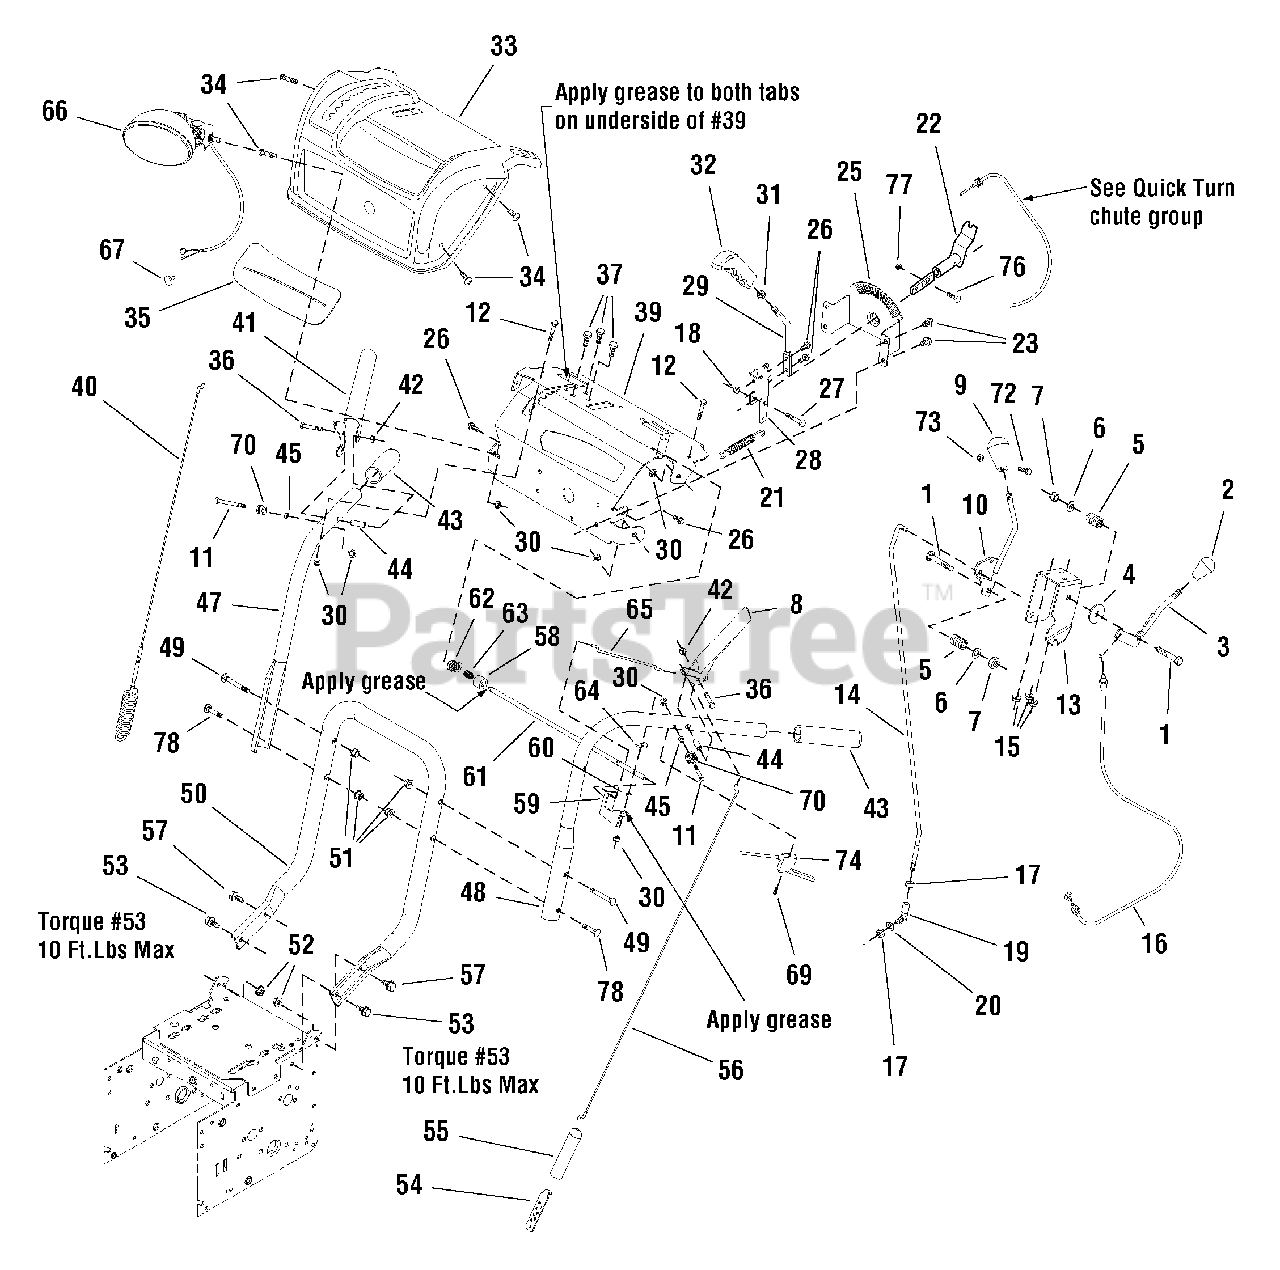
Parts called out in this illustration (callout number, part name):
1	CAPSCREW, Hex Head 3/8-16 x 2 G5
2	KNOB, Interior Thread 3/8-16
3	ROD, 3/8 Diameter 5" Large, 3/8-16 x 1 Chute
4	WASHER, 3/8
5	SPRING
6	WASHER, 3/8
7	NUT, Hex Lock ESNA Light 3/8-16
8	HANDLE, Clutch L.H.
9	KNOB, Slot Speed
10	ROD & PLATE ASSEMBLY, Speed Control
11	CAPSCREW, Hex Head 1/4-20 x 2-1/2 G5
12	CAPSCREW, Hex Head 1/4-20 x 1-3/4 G5
13	BRACKET, Trac & Deflector Control
14	ROD, Speed Control
15	NUT, Hex Flange 5/16-18, Whiz Lock, Small
16	CABLE, Deflector Control
17	NUT, Hex 5/16-24
18	NUT, Hex Flange 1/4-20 Centerlock Large
19	BALLJOINT, Steel
20	LOCKWASHER, Spring 5/16
21	SPRING, Extension
22	TUBE & BRACKET ASSEMBLY, Cable Support
23	SCREW, Hex Washer Head Taptite 5/16-18 x 1/2
25	SUPPORT, Chute Control 14GA
26	SCREW, Hex Washer Head Taptite 1/4-20 x 5/8
27	BOLT, Shoulder 1/4-20
28	BRACKET, Support Quick Turn
29	ROD, Chute
30	NUT, Hex Lock ESNA Light 1/4-20
31	NUT, Hex Jam 3/8-16
32	GRIP, Lever
33	COVER, Panel
34	SCREW, Truss Head Torx Drive 1/4-20 x 3/4
35	BELLOWS, Black Rubber Quick Turn
36	CAPSCREW, Hex Head 1/4-20 x 1-1/2 G5
37	CARRIAGE BOLT, 5/16-18 x 3/4 G5
39	SUPPORT, Dash Panel Cover
40	CABLE & SPRING ASSEMBLY, Auger Drive R.H.
41	HANDLE, Clutch R.H.
42	NUT, Hex Centerlock 1/4-20
43	GRIP
44	SPACER
45	SPACER
47	HANDLE, Upper R.H.
48	HANDLE, Upper L.H.
49	CARRIAGE BOLT, 5/16-18 x 2-1/4 G5
50	HANDLE, Lower
51	NUT, Hex Flange 5/16-18
52	NUT, Hex Flange 5/16-18 Two-Way Lock
53	SCREW, Hex Washer Head Taptite 5/16-18 x 3/4
54	BRACKET, Cable Adjusting
55	BOOT, Spring End Cover
56	CABLE,
57	CAPSCREW, Hex Head 5/16-18 x 1 G5
58	SPACER, Powdered Metal
59	BRACKET, Free Hand Control 12GA
60	SPACER, Powdered Metal
61	ROD & SPRING ASSEMBLY, w/Pin
62	WASHER, 1/2
63	SPRING, Compression
64	WASHER, 1/4
65	ROD, Hold Down E-Coat
66	HEADLIGHT ASSEMBLY, Oval, Clear
67	FASTENER, Panel
69	SCREW, Pan Head Torx #10 x 1/2 Thick Cut
70	SPOOL CABLE, Auger Control
72	SCREW, Round Head Phillips #10-24 x 3/4
73	NUT, Hex Lock 10-24 w/Nylon Insert
74	CABLE & HANDLE ASSEMBLY
76	CARRIAGE BOLT, 1/4-20 x 3/4
77	NUT, Center-Lock, 1/4-20
78	BOLT, Carriage, 5/16-18 x 1-3/4
